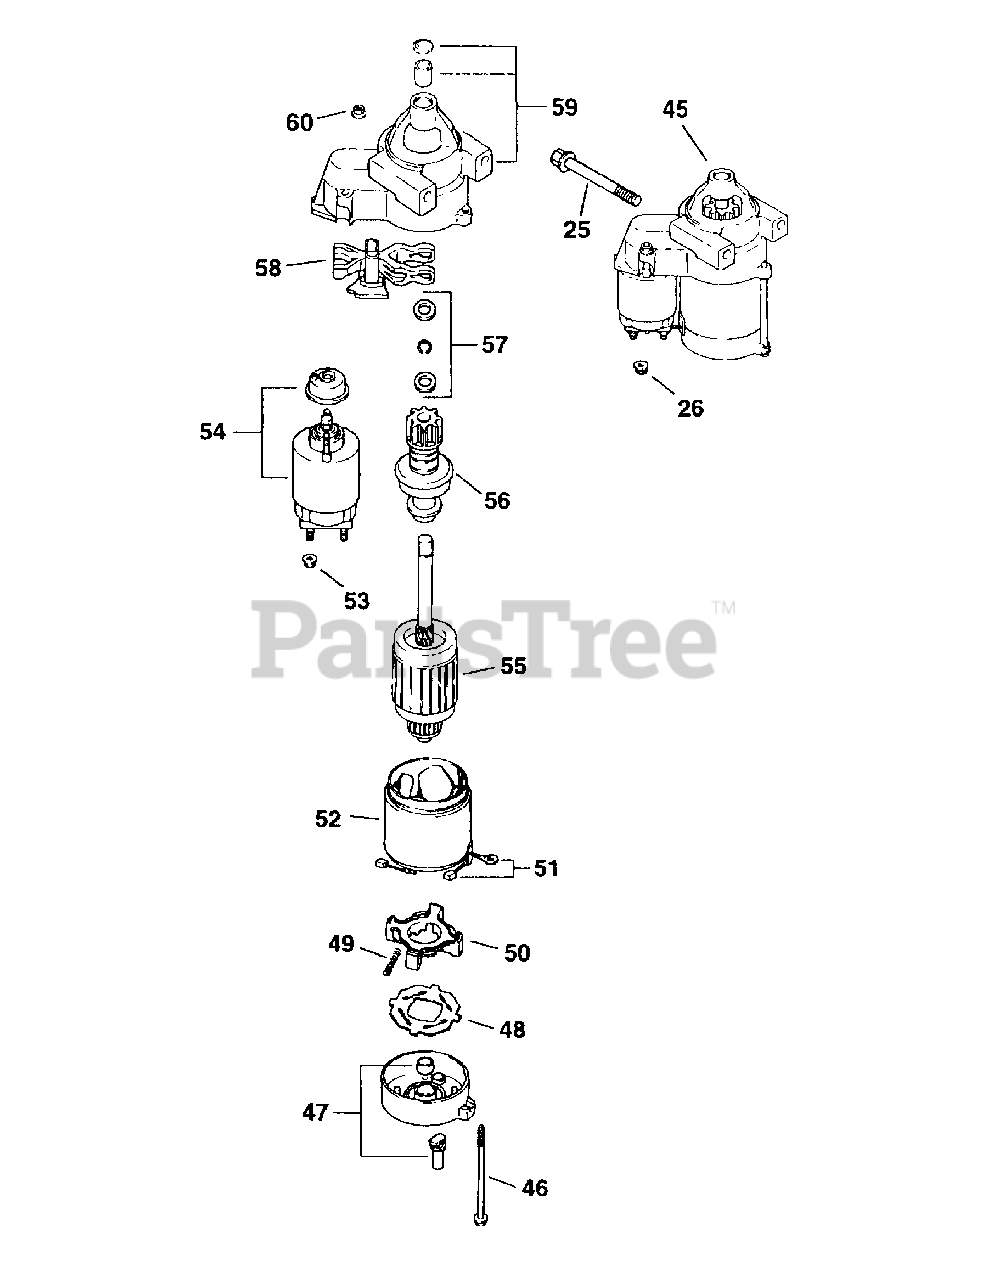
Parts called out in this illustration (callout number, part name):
25	Screw, Hex Flange
26	Nut, Hex Flange
45	Starter, Solenoid Shift
47	Cap, Commutator End
48	Insulator
49	Spring, Brush
50	Holder, Brush
51	Kit, Brush
53	Nut, Starter
54	Solenoid
55	Armature, Starter
56	Drive, Pinion
58	Lever, Starter Drive
59	Cap, Drive End
60	Nut, Starter
